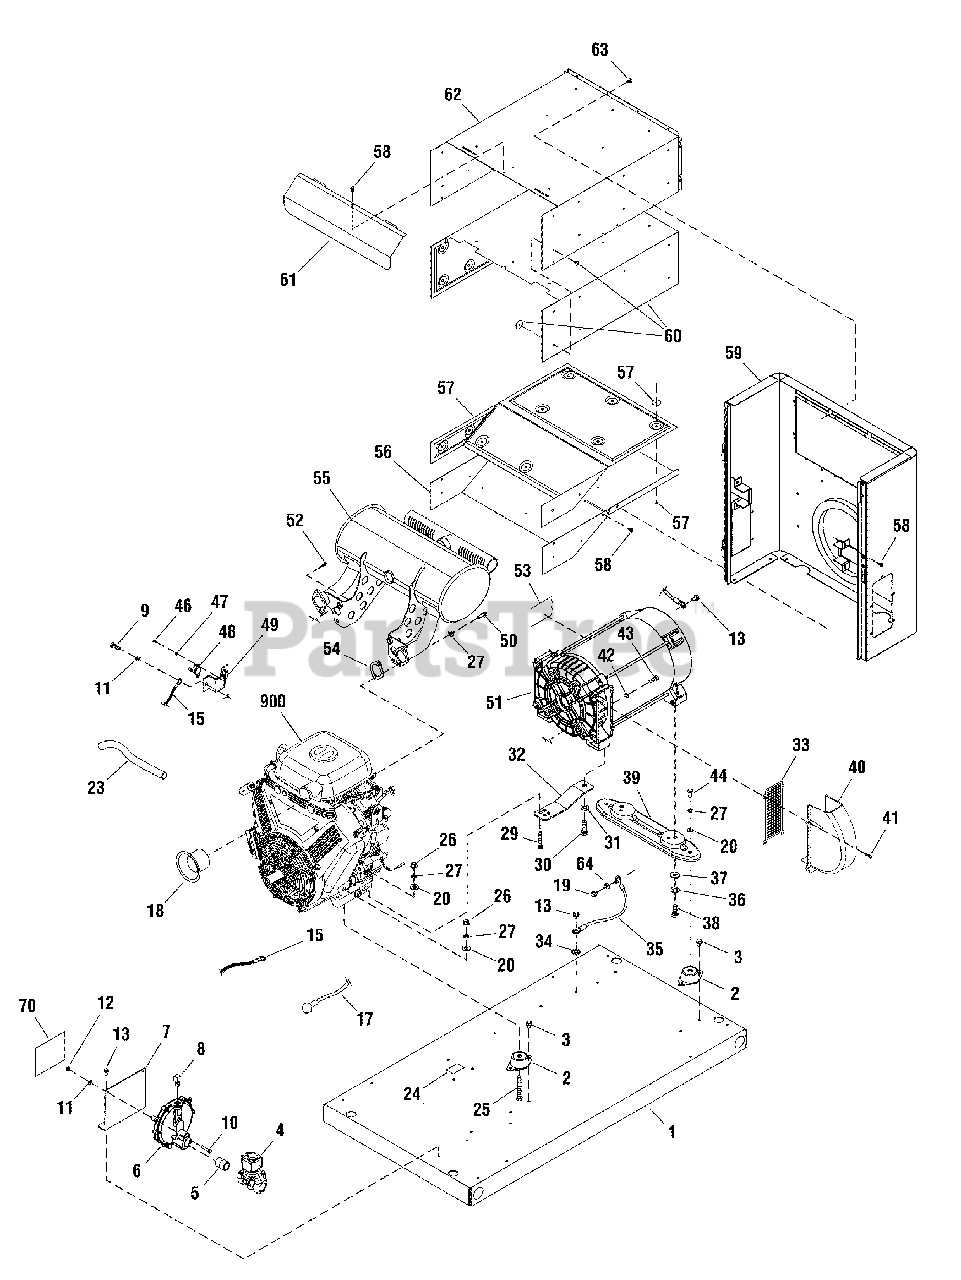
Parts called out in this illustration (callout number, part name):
2	MOUNT, Vibration
4	SOLENOID, Gas Fuel
6	REGULATOR, NG/LPG
9	* CAPSCREW, M6-1.0 x 16
10	* CAPSCREW, M6-1.0 x 30
11	* WASHER, Lock, 1/4
12	* NUT, M6-1.0
13	BOLT
15	CABLE, Battery, Black
17	CABLE, Battery, Red
20	* WASHER, FLat, 5/16-M8
23	HOSE, Oil Drain
24	DECAL
25	* CAPSCREW, Hex Head, 5/16-18 x 2-1/2
26	* NUT, 5/16-18
27	* WASHER, Lock, 5/16-M8
29	* CAPSCREW, Hex Head, 5/16-18 x 2
30	* CAPSCREW, Hex Head, M12-1.75 x 35
31	* WASHER, M12
32	SUPPORT, Engine
34	* WASHER, Shakeproof, M6-1/4
36	* WASHER, Lock, 3/8
37	* WASHER, Flat, 3/8
38	* CAPSCREW, Hex Head, 3/8-16 x 1
39	SUPPORT, Engine
41	* SCREW, Taptite, M5-0.8 x 10
42	* WASHER, Lock, 3/8
43	* CAPSCREW, Socket Head, 3/8-16 x 1-1/4
44	* CAPSCREW, Hex Head, 5/16-18 x 3/4
46	* SCREW, Pan Head, 4-40 x 0.19
47	* WASHER, Lock, #4
49	PLATE, Temp Switch
50	SCREW
51	ALTERNATOR
53	DECAL
59	BULKHEAD, Alternator
62	BOX, Muffler Top
64	* WASHER, Shakeproof, M6
900	** ENGINE
